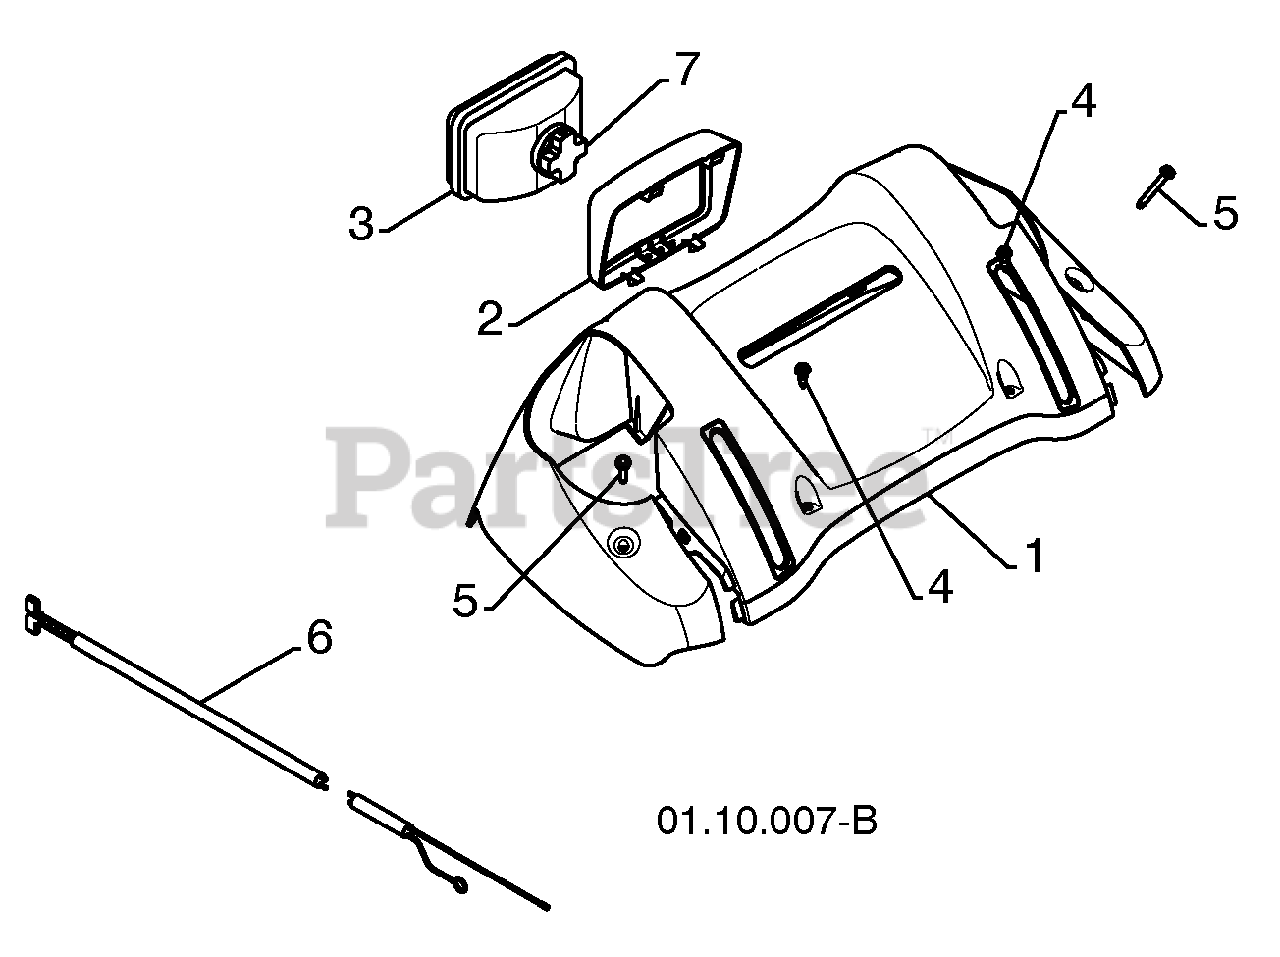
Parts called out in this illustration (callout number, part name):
1	CONSOLE PANEL
2	HEADLIGHT BEZEL
3	FLOOD HEADLIGHT
4	SHOULDER SCREW 10-24 X .625
5	SCREW 10-24 X 1.25
6	WIRE HARNESS
7	BULB
